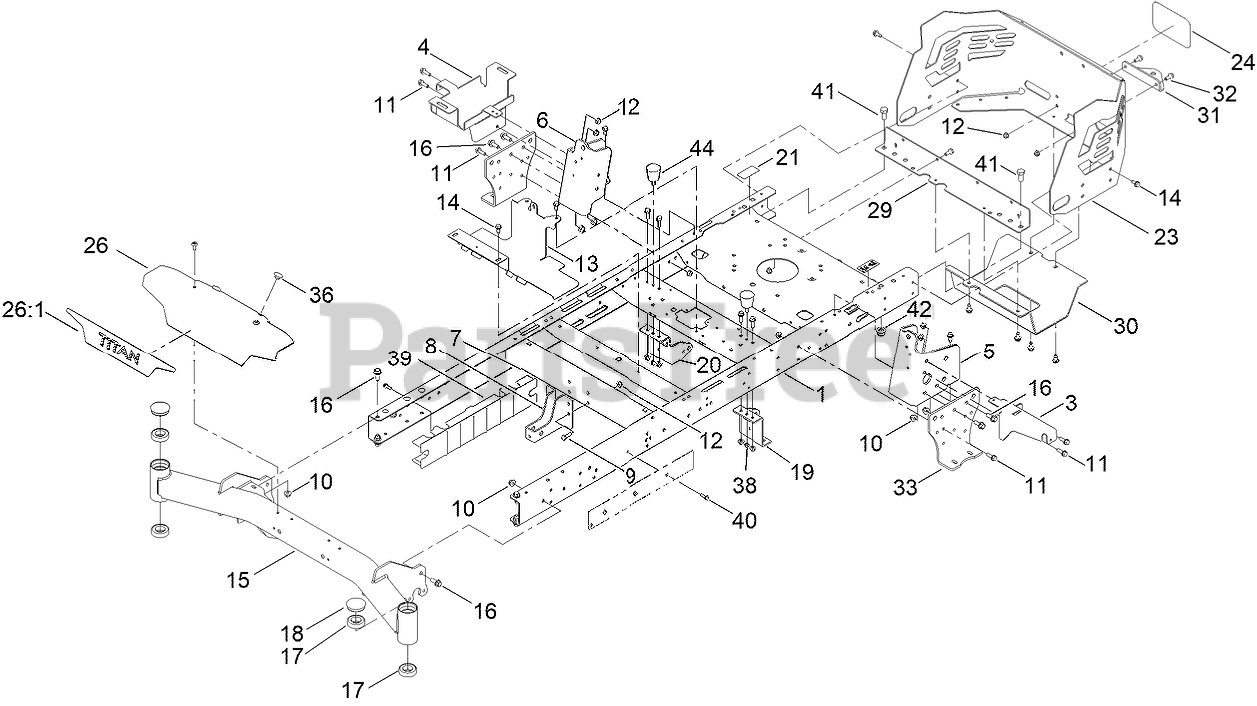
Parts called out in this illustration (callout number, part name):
1	FRAME ASM
3	BRACKET-SUPPORT, POD (LH)
4	TRAY-BATTERY
5	BRACKET-MOUNTING, LH
6	BRACKET-MOUNTING, RH
7	BRACE-CROSS, LOWER
8	BRACKET-MOUNT DAMPER, LOWER
9	SCREW-HH
10	NUT-HF, NI
11	SCREW-HHF
12	NUT-HF, NI
13	BRACKET-MOUNT
14	SCREW-HWHTF
15	FRONT AXLE ASM
16	SCREW-HHF
17	BEARING-BALL
18	CAP-GREASE
19	MOUNT-HYDRO, FRONT (LEFT)
20	MOUNT-HYDRO, FRONT (RIGHT)
21	DECAL-BYPASS
23	GUARD-ENGINE
24	DECAL
26	PLATE-FRONT
26:1	PLATE-FRONT
29	CROSSMEMBER-REAR, WIDE
30	GUARD-MUFFLER
31	BRACKET-HITCH
32	SCREW-HHF
33	MOUNT-HYDRO
36	BUMPER-SEAT
38	NUT-LOCK, NI
39	GUARD-RAIL
40	SCREW-HWH
41	SCREW-HH
42	NUT-LOCK
44	BUMPER-RUBBER
